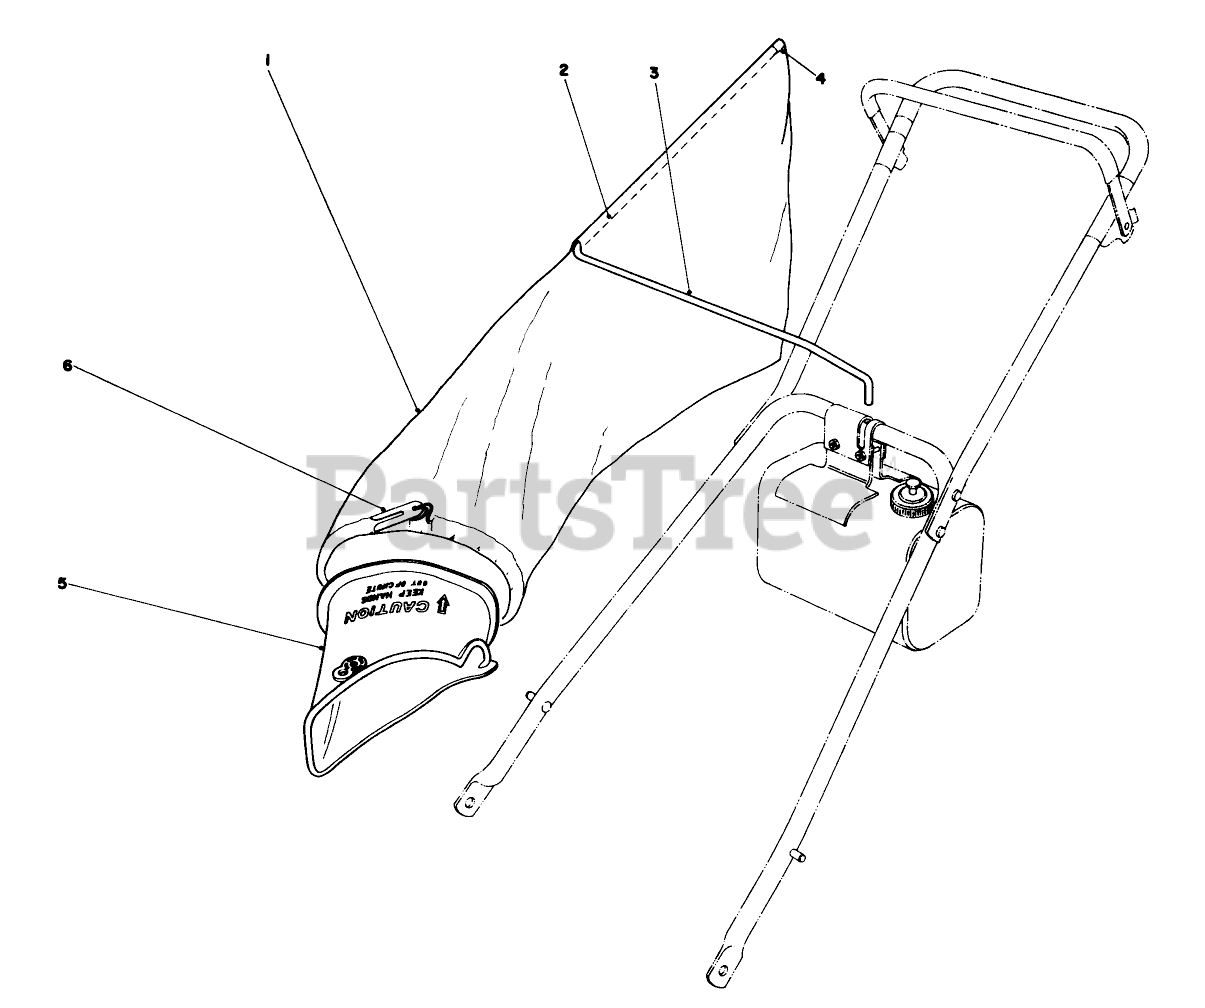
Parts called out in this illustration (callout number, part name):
1	Giant Bag Replacement (Incl. Ref #6)
3	Hanger Rod
5	Bag Chute
6	BAG CORD FASTENER
